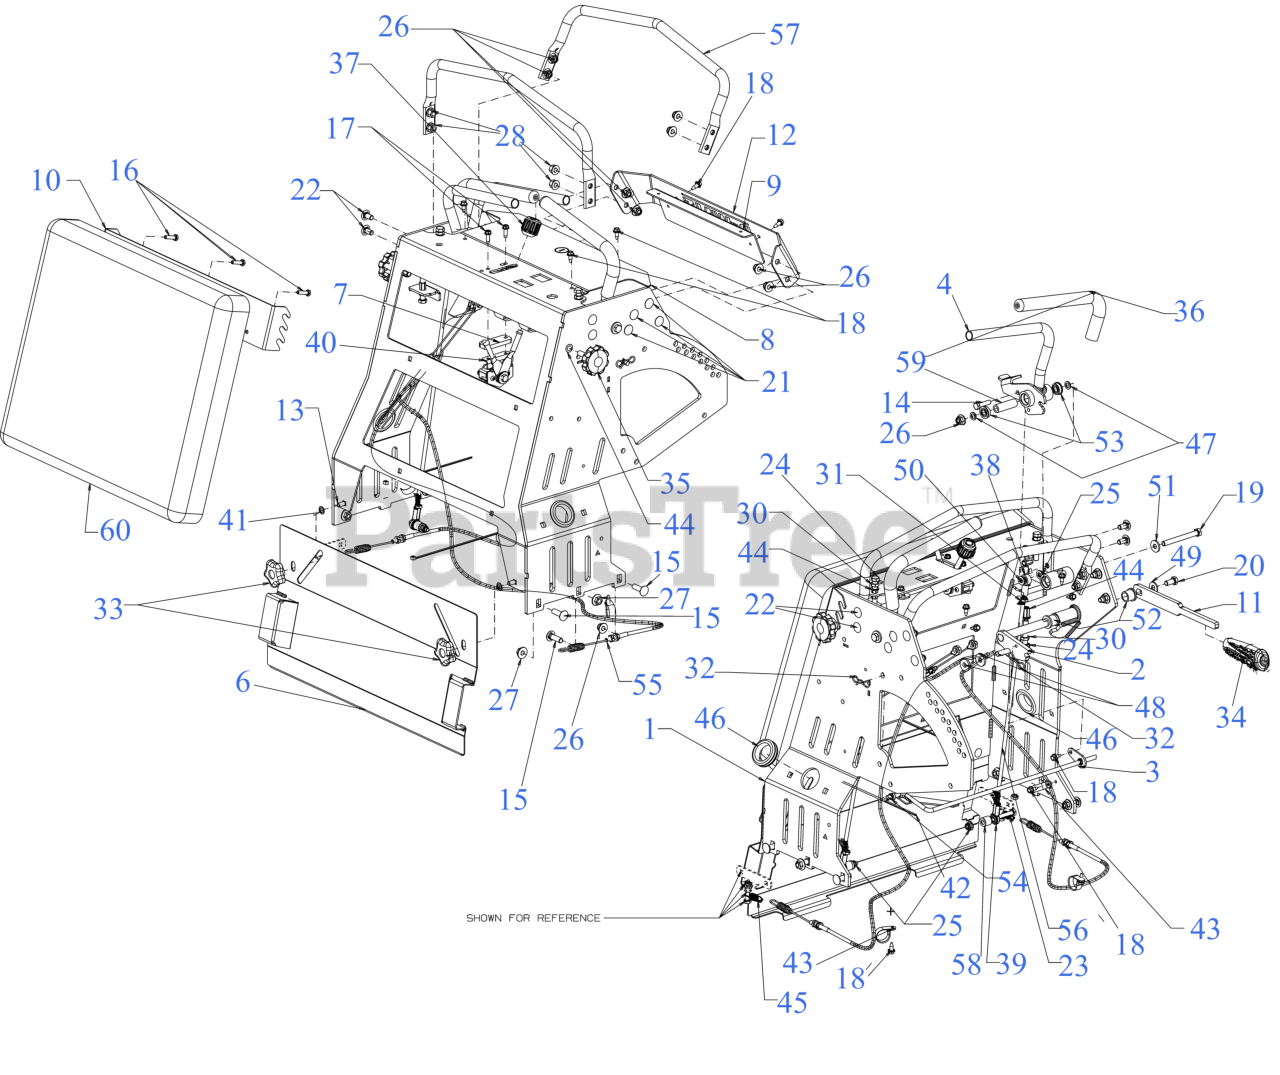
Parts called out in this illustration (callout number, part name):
1	CONTROL BASE
2	BRAKE PIVOT
3	CONTROL LOCK ROD
4	CONTROL HANDLE (LH)
4	CONTROL HANDLE (RH)
6	PANEL COVER
7	THROTTLE CABLE SPACER
8	DASH PANEL
9	DASH SUPPORT
10	PAD MOUNT
11	BRAKE HANDLE
12	CONTROL BASE (FRONT)
13	CARRIAGE BOLT 5/16-18 x .75
14	SCREW 5/16-18 x 1.25 GR5
15	CARRIAGE BOLT 3/8-16 X1.25 GR5
16	SCREW 1/4-20 X1.00 GR5
17	SCREW 1/4-20 x .750
18	SCREW 1/4-20X.625
19	SCREW 3/8-16 x 3.50 GR5
20	SCREW 3/8-16 x .75 GR 5
21	CARRIAGE BOLT 3/8-16 x 1.00 GR5
22	CARRIAGE BOLT 3/8-16 x .75
23	SCREW 5/16-18 x 1.75 GR5
24	SCREW 3/8-16 x 2 GR5
25	FLANGE LOCK NUT 5/16-18
27	FLANGE LOCK NUT
28	NUT-CTRLCK FLG HEX
29	HEX JAM NUT 5/16-24 GR5
30	HEX NUT
31	HEX JAM NUT 5/16-24 GR 5
32	PIN:COTTER
33	STAR KNOB 5/16-18
35	STAR KNOB 3/8-16
36	GRIP .75 ID X 1.00 OD
37	BALL KNOB
38	ROD END 5/16 ID
39	END ROD- 5/16 (LH)
40	ELECTRONIC THROTTLE CONTROL
41	PUSH NUT
42	TIE CABLE 8.5 LG
43	DRAIN HOSE CLAMP
44	RIV NUT 3/8-16
45	EXTENSION SPRING .500 OD x 1.71
46	RUBBER GROMMET (1.50X2.13X.563)
47	FLAT WASHER
48	FLAT WASHER .385 x 1.00 x .135
49	FLAT WASHER .385X.870X.090
50	FLAT WASHER
51	WASHER
52	FLANGE BEARING
53	FLANGE BEARING
54	BUSHING .3135ID
55	BRAKE CABLE
56	CONTROL ROD
57	TUBE
58	SPACER .34 x .75 x .63 LG
59	SPACER .379 x .63 x 1.957
60	LEG PAD
